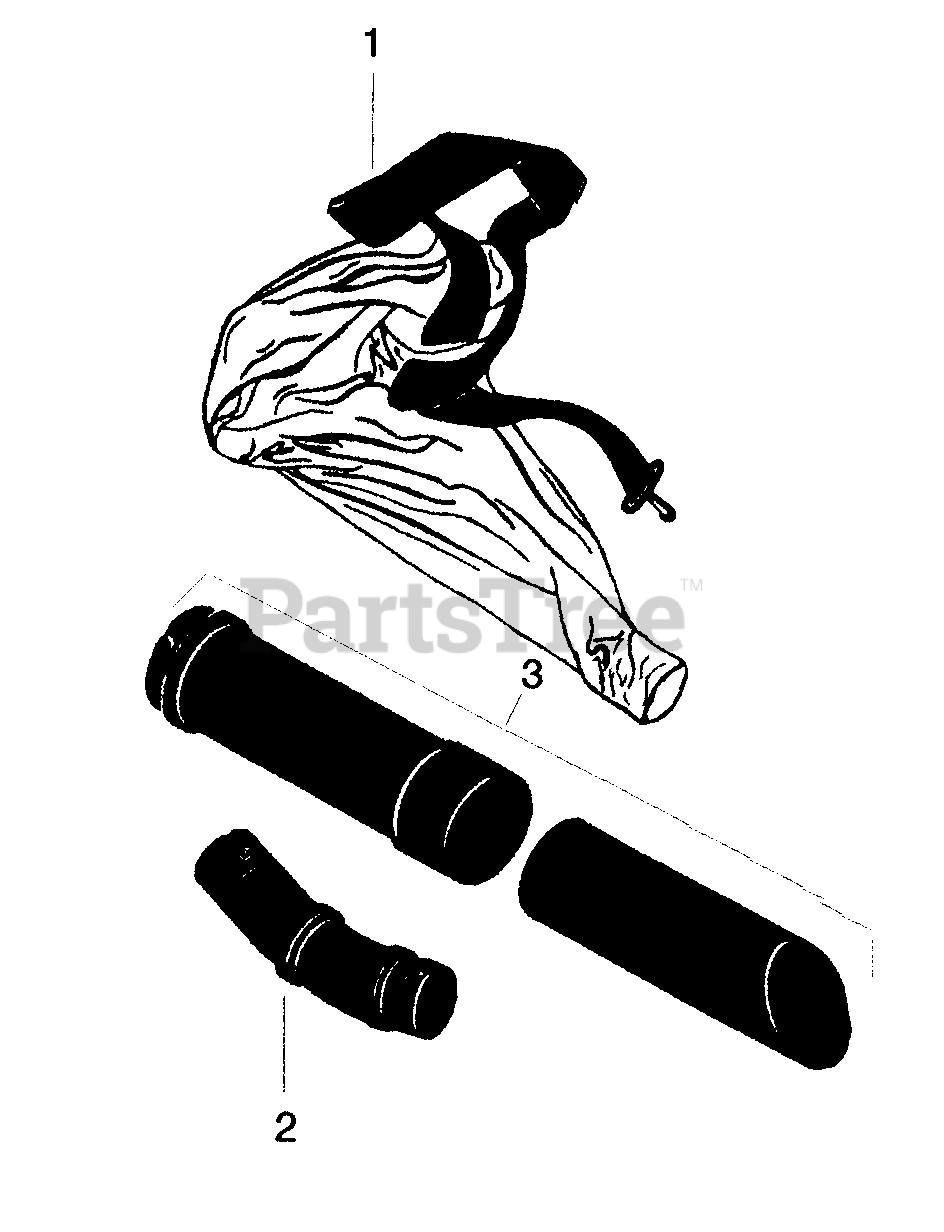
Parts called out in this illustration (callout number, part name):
1	Vac Bag Assy. w/Strap
2	Elbow-Vac Bag
3	Vac Tube Ass'y.
